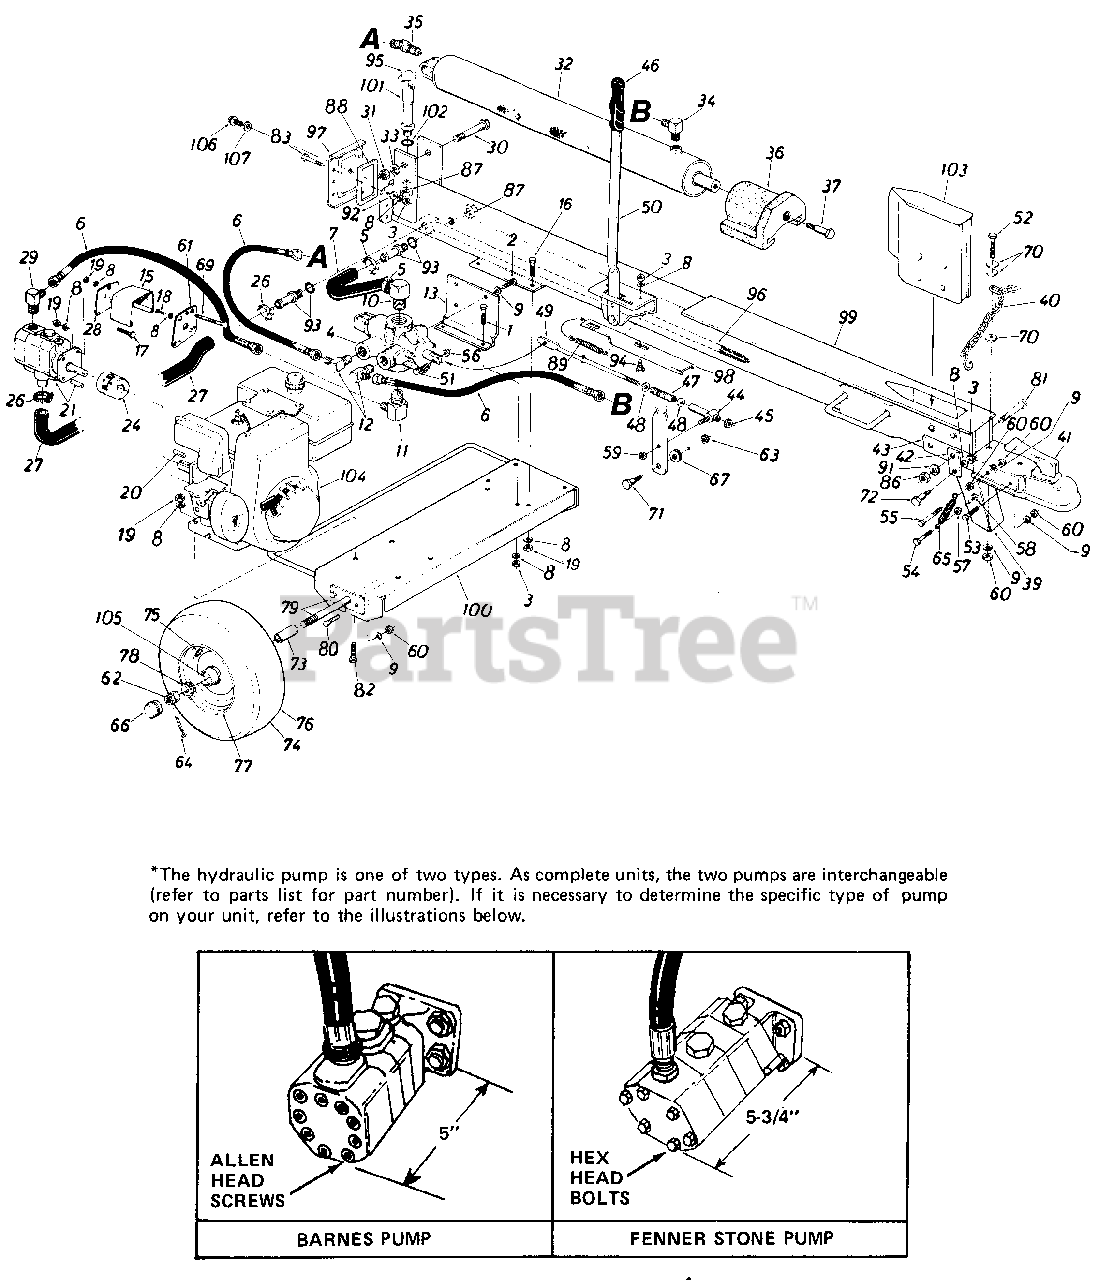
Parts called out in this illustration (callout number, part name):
1	Hex Bolt 5/16-18 x .75" Lg.*
2	Hex Bolt 3/8-16 x .50"Lg.*
3	Hex Nut 5/16-18 Thd.*
4	Control Valve 400
5	Hose Clamp 5/8"
6	High Pressure Hose Ass'y. .38" I.D.
7	Return Hose - Valve to Tank 3/4" I.D.
8	L.Wash. 5/16" I.D.*
9	L.Wash. 3/8" I.D.*
10	Return Elbow
11	90ø Solid Male Adapter
12	90ø Solid Male Adapter
13	Valve Mtg. Plate
15	Coupling Shield
16	Hex Bolt 5/16-24 x 1.00" Lg.*
17	Hex Bolt 5/16-24 x .75" Lg.*
18	Hex Bolt 5/16-24 x .6'7" Lg.
19	Hex Nut 5/16-24 Thd.*
20	Sq. Key 3/16" x 2.25" Lg.
21	Pump with Woodrull Key
24	Flexible Coupling Comp.
26	Hose Clamp 5/8"
27	Suction Hose 1.0" Dia.
29	90ø Solid Male Adapter
30	Hex Bolt 3/4" x 4.0" Lg.
31	Hex Nut 3/4" Thd.
32	Hydraulic Cylinder 3-1/2" Dia.
33	L.Wash. 3/4" I.D.*
34	High Pressure 90ø Elbow
35	45ø Male Adapter 3/4-16 MJ-3/8-18 NP
36	Pusher Plate
37	Shoulder Bolt. .62" Dia. x 4.75" Lg. (1/2-13 Thd.)
39	Flip Stand Bracket
40	Chain-Tow Hitch
41	Tow Hitch Ass'y. Comp.
42	Stand Pivot Bracket
43	Tow Hitch Brk't 2 x 3/16 10.25" Lg.
44	Ferrule Ass'y.
45	Hex Cent. L.Nut 3/8-24 Thd.
46	Grip-Black Vinyl
47	Compression Spring
48	Special Washer .378 x 1.00" x .125 Thd.*
49	Engagement Rod 3/8" Dia. x 9.0" Lg.
50	Engagement Handle
51	Hex Bolt 1/4-20 x 1.75" Lg.
52	Hex Bolt 3/8-24 x 1.25" Lg.*
53	Hex Bolt 3/8-24 x .75"4.*
54	Hex Bolt 1/4-28 x 1.00" Lg.*
55	Hex Bolt 3/8-24 x 1.75" Lg.(Grade 5)
56	Hex Patch L.Nut 1/4-20 Lg.*
57	Hex Cent. L.Nut 1/4-28 Thd.
58	Hex Nut 1/4-28 Thd.
59	Hex Cent. L.Nut 5/16-18 Thd.
60	Hex Nut 3/8-24 Thd.*
62	Hex Castle Nut 3/4-16 Thd.
63	Hex L.Nut 3/8-16 Thd.
64	Coter Pin 5/32" Dia. x 1.25" Lg.*
65	Extension Spring .50" O.D. 3.97" Lg.
66	Hub Cap
67	Rubber Washer
69	Hex Bolt 5/16-24 x 4.0" Lg *
70	Fl.Wash. .375" I.D. x .870" O.D. x .090
71	Shoulder Bolt .498" Dia. x .340" Lg.
72	Shoulder Bolt .437" Dia. x .268" Lg.
73	Spacer.75" I.D. x 1.12" O.D. x 1.56" Lg.
75	Air Valve-Tubeless
76	Tire Only 16.0 x 4.0-2 Ply
78	Roller Rearing 3/4" I.D.
79	Axle Ass'y. .75" Dia. x 35.25" Lg.
80	Hex Bolt 3/8-24 x 1.0" Lg.
81	Hex Bolt 5/8-18 x 3.50" Lg.*
82	Hex Bolt 5/16-24 x 1.75 Lg.*
83	Hex Bolt 5/16-18 x 1.50" Lg.*
86	Hex Nut 5/1-1 Thd.*
87	Hex Nut 11/16-12 Thd.
88	Gasket 2.62 x 5.12
89	Extension Spring .50" O.D. x 4.25" Lg.
91	L.Wash. 5/8" I.D.*
92	Fl.Wash. .34" I.D. x.68" O.D. x .062 Thk.
93	Adapter 1.0" Tube 11/16-12 "O" Ring
94	Shoulder Bolt .437" Dia. x .180" Lg.
95	Breather Cap
96	Strainer Tube Ass'y.
97	End Plate
98	Engagement Brk't. 1.39 x 11.75" Lg.
99	Complete Oil Tank Ass'y.
100	Engine Frame Ass'y.
101	Filler Tube Ass'y.
102	"O"Ring 92" I.D. x 1.16" O.D. x .116 Dia.
103	Wedge Ass'y.
104	5 H.P. Engine
105	Bearing Seal
106	Hex Hd. .Tap Scr. 5/16"
107	Gasket
